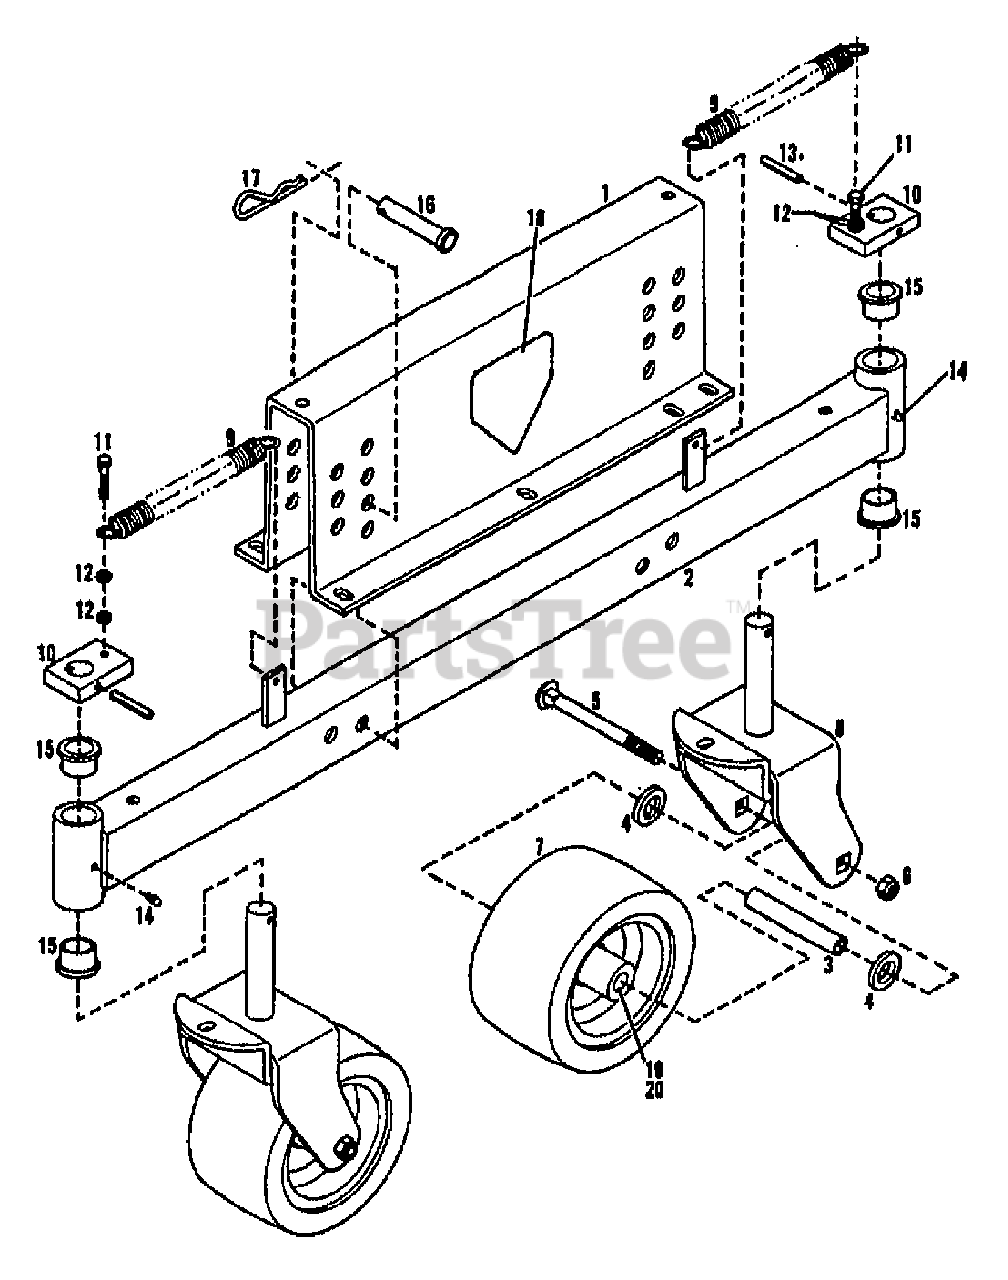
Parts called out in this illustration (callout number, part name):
1	MOUNT-GAGE WHEEL W/DECALS
2	SUPPORT-GAGE WHEEL
3	SLEEVE-WHEEL
4	WASHER-1.5X.812X.134 ZP
5	SCR-CARR 1/2-13X4.75
6	NUT-TOP LOCK 1/2-13 ZP
7	ASSM-TIRE&WHEEL 6.25X3.
8	YOKE-WHEEL
9	SPRING-EXTENSION
10	ARM-CENTERING
11	SCR-HH 1/4-20X1.25
12	NUT-HEX 1/4-20 ZP
13	PIN-DRIVE .25X1.5
14	FITTING-GREASE 1/4-28X2.00
15	BEARING-FLANGE
16	PIN-CLEVIS .62X2.50 ZP
17	PIN-HITCH .149DIA
18	DECAL, DANGER
19	BEARING-ROLLER
20	CAP-BEARING
